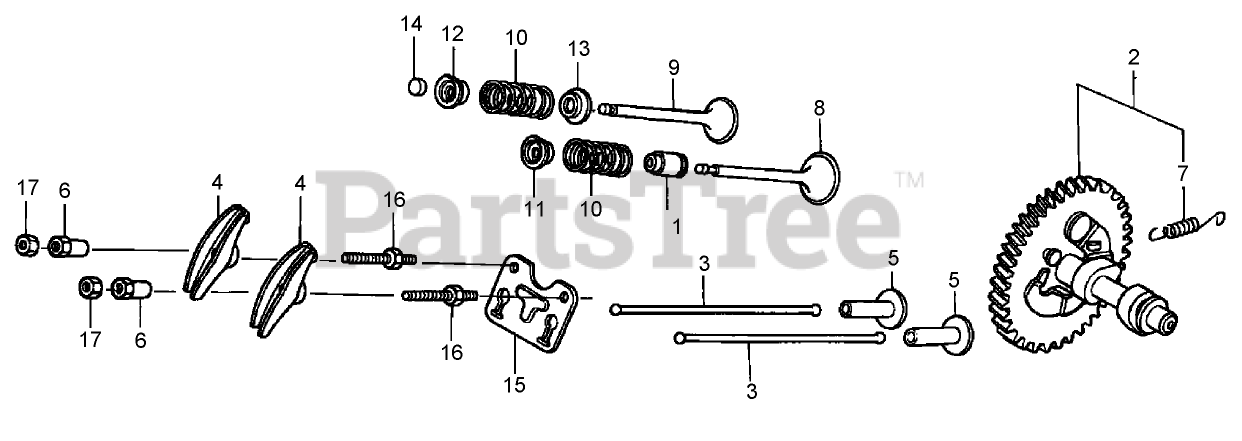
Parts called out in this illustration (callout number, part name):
1	SEAL-STEM, VALVE
2	CAMSHAFT ASM
3	ROD, PUSH
4	ARM-ROCKER, VALVE
5	LIFTER-VALVE
6	PIVOT-ARM, ROCKER
7	SPRING-RETURN, WEIGHT
8	VALVE-INTAKE
9	VALVE-EXHAUST
10	SPRING-VALVE
11	RETAINER-VALVE, INTAKE
12	RETAINER-VALVE, EXHAUST
13	SEAT-SPRING, VALVE
14	ROTATOR-VALVE
15	PLATE-PUSH ROD
16	BOLT-PIVOT (8 mm)
17	NUT-ADJUSTING, PIVOT
